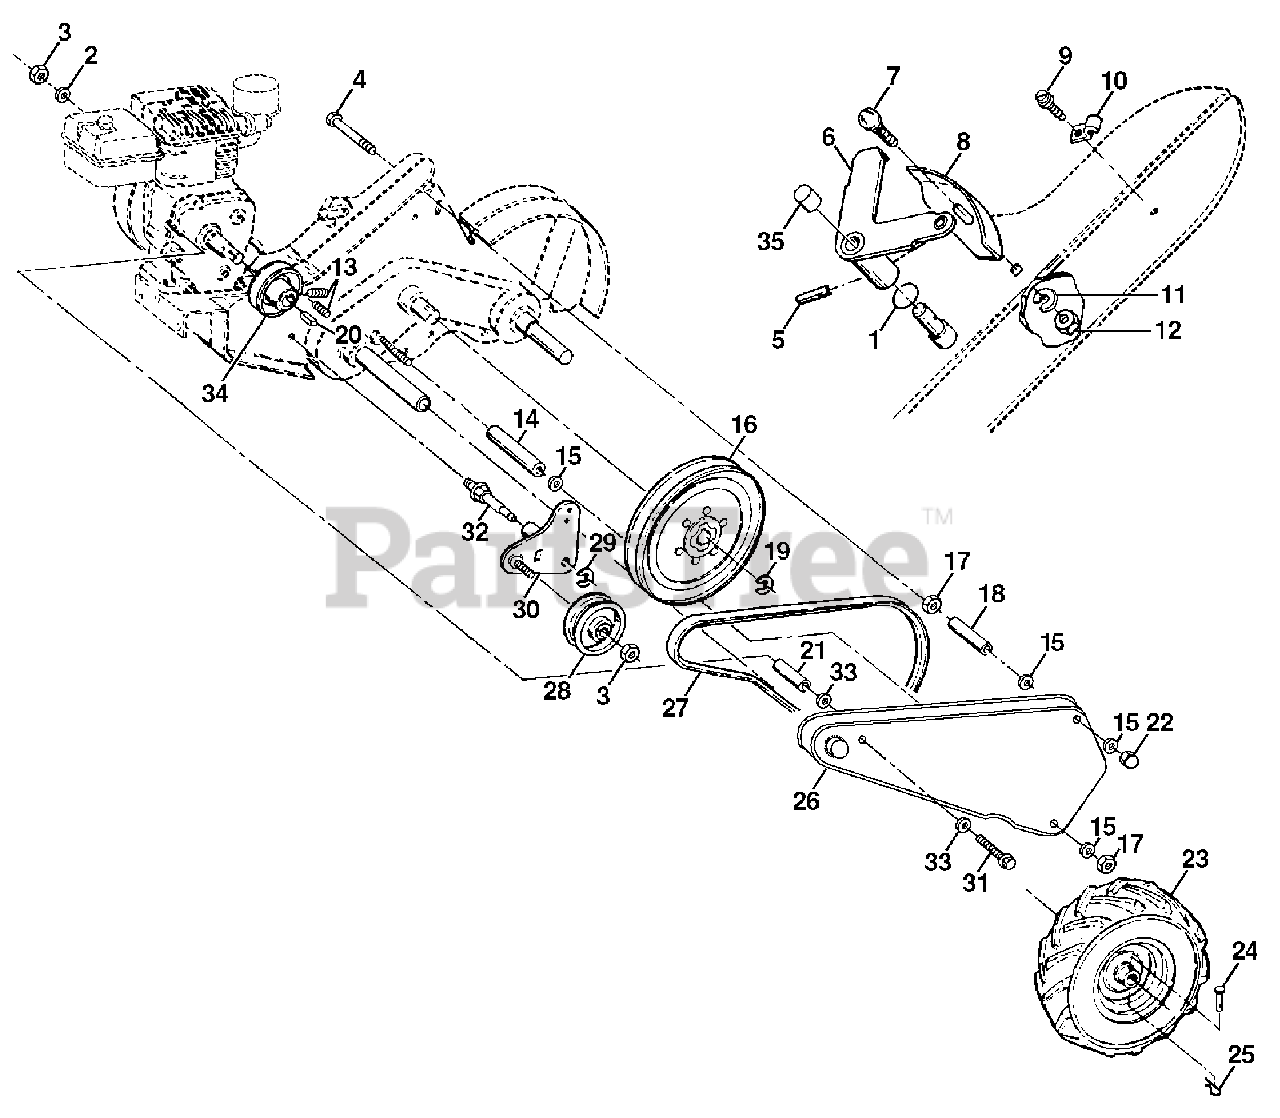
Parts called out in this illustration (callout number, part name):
2	Washer, Lock 3/8
3	Nut, Hex 3/8-160
4	Bolt, Hex Head 5/16-18 x 4-1/2
5	Pin, Roll
6	Lever, Shift
7	Bolt, Carriage 1/4-20 x 1/2 Grade 5
8	Plate, Shift Indicator
9	Screw, Hex Washer Head, Slotted #10-24 x 1/2
11	Washer, Lock 1/4
12	Nut, Hex 1/4-20
13	Screw, Set, Hex 5/16-18 x 3/8
14	Spacer, Split
15	Washer 11/32 x 11/16 x 16 Gauge
16	Sheave, Transmission
17	Nut, Hex 5/16-18
19	Ring, Retainer
20	Key, Square
21	Spacer, Split .523 x .718 x 2
22	Nut, Cap 5/16-18
23	Rim
23	Tire Valve
24	Rivet, Drilled
25	Clip, Hairpin
26	Guard, Belt
28	Pulley, Idler
29	Ring, Klip
30	Bracket, Idler
31	Bolt, Hex Head 1/2-20 x 2-3/4
32	Shaft, Idler Arm
33	Washer
34	Sheave, Engine
35	Cap, Plunger
